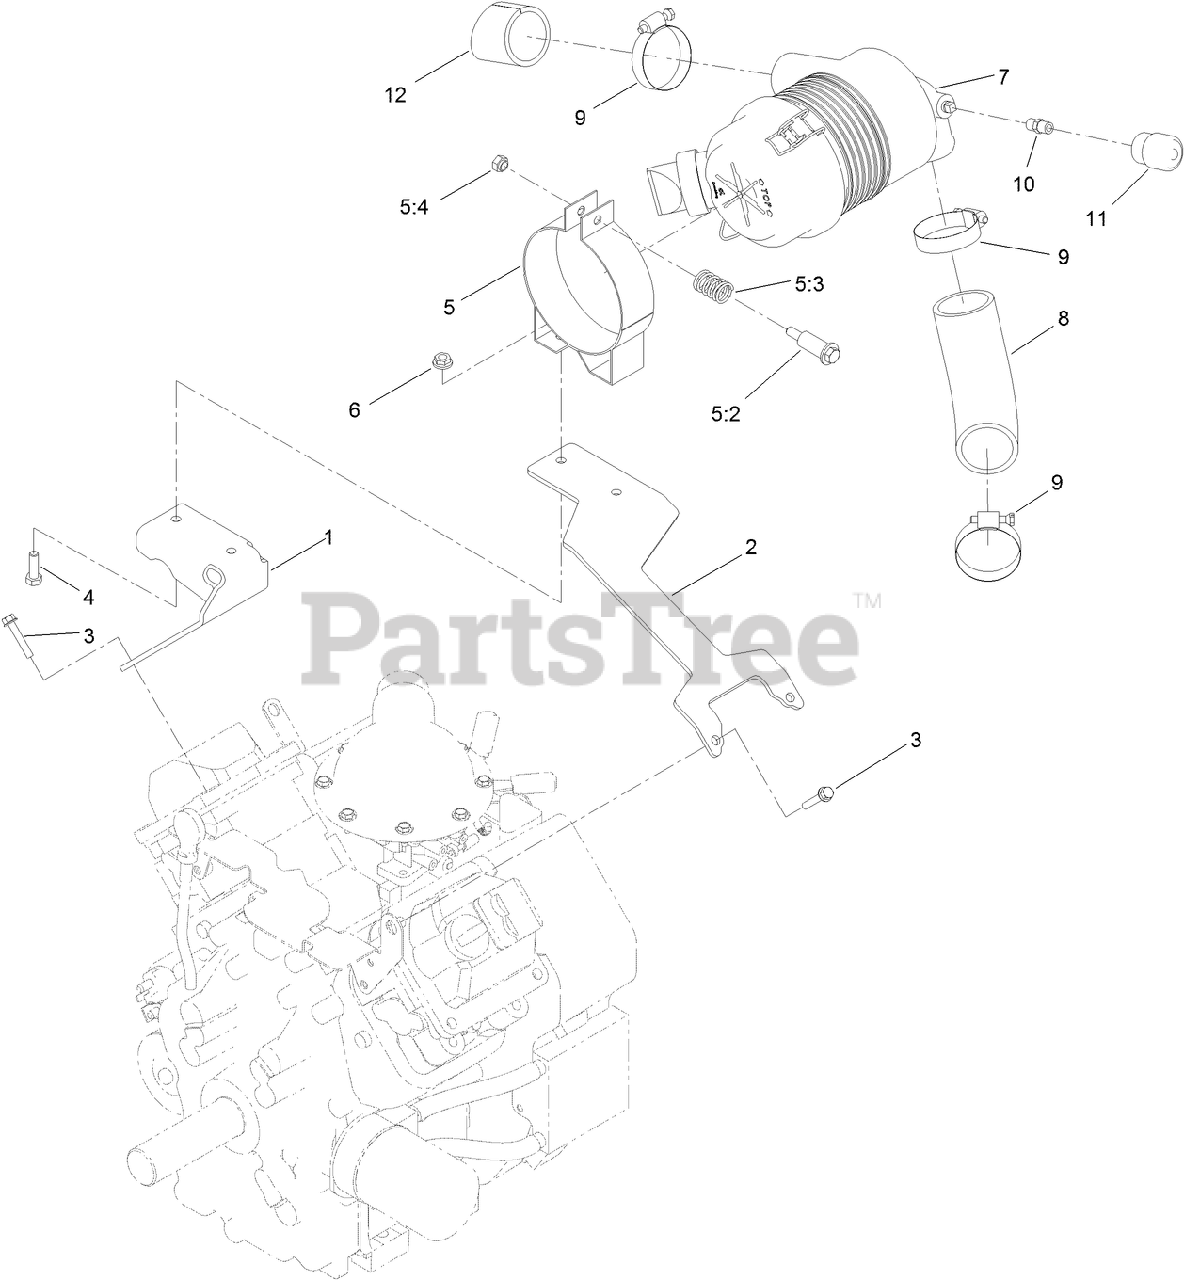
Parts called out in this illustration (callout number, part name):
1	BRACKET-SUPPORT, RIGHT
2	BRACKET-SUPPORT, LEFT
3	SCREW-HHF
4	SCREW-HH
5	AIR CLEANER MOUNTING BAND ASM
5:3	SPRING
5:4	NUT
6	NUT-HF
7	AIR CLEANER ASM
8	HOSE-AIR CLEANER
9	CLAMP-HOSE
10	Nipple-Pipe
11	INDICATOR-MINI
12	TUBE-INLET, AIR
